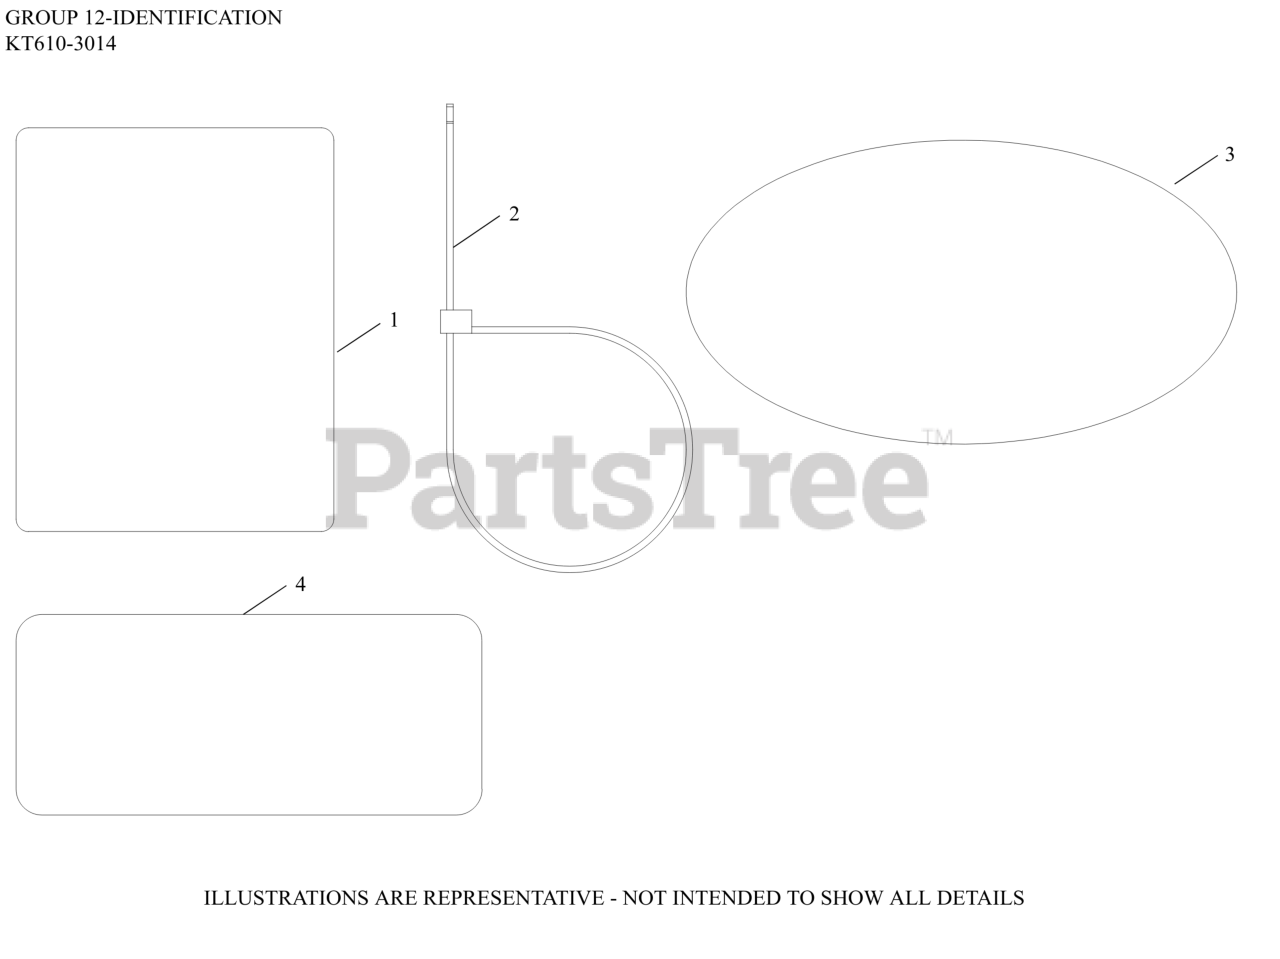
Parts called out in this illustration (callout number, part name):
1	LABEL, CLEAR LAMINATION
3	LABEL, 6600 SERIES (19HP)
3	LABEL, PRO PERFORMANCE FILTRATION SYSTEM
4	LABEL, CANADIAN COMPLIANCE
